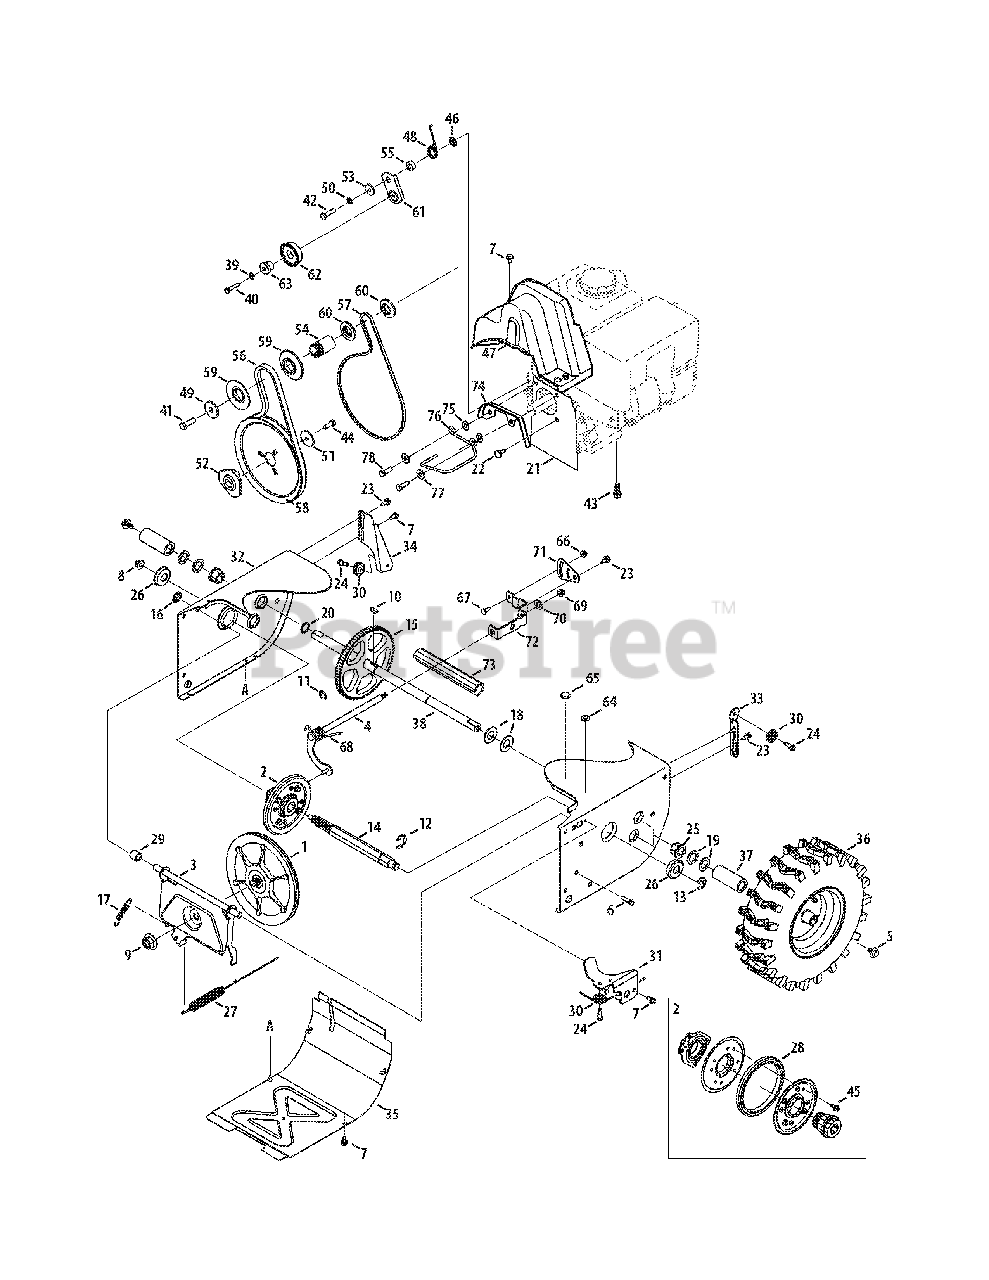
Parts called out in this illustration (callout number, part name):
1	Disc Assembly, Friction Wheel
2	Friction Wheel Assembly, 5.5 OD
3	Support Bracket, Friction Wheel
4	Shift Assembly, Rod
5	Screw, 5/16-24, .750, Gr5
6	Screw, 1/4-20, 1.000
7	Screw, 1/4-20 x .625
8	Nut, Flange Lock, 3/8-16, Nylon
9	Nut, Flange, 5/8-18
10	Key, Hi Pro, 3/16 x 3/4 Dia.
11	E-ring, .500 Dia.
12	E-ring, Retaining, .875 Dia.
13	E-ring, .750 Dia.
14	Hex Shaft, .8125, 7-Tooth
15	Gear, 80-Tooth
16	Speed Nut, .500
17	Extension Spring
18	Washer, Flat, .760 x 1.490 x .060
19	Washer, Flat, .793 x 1.24 x .060
20	Washer, Flat, .75 x 1.00 x .060
21	Plate, Cover
22	Shoulder Screw
23	Screw, Shoulder, .37 x .105, 1/4-20
24	Screw, 1/4-28, .375
25	Bearing, Hex Flange x .75 ID
26	Bearing, Ball, 17 x 40 x 12
27	Clutch Cable, Wheel, 44.95"
28	Rubber, Friction Wheel, 5.5 OD
29	Spacer, .508 ID x .75 OD x .68
30	Roller, Cable
31	Front Guide Bracket, Auger Cable
32	Frame
33	Guide Bracket, Auger Cable
34	Guide Bracket, Drive Cable
35	Cover, Frame
36	LH Wheel Assembly
36	RH Wheel Assembly
37	Spacer, 1.25 x .75 x 3.0
38	Axle, .75 x 22"
39	Washer, Lock, 1/4
40	Hex Screw, 1/4-20, 1.25, Gr5
41	Hex Screw, 3/8-24, 1.25, Gr8
42	Hex Screw, 5/16-24, 1.25, Gr5
43	Screw, Sems, 3/8-16, 1.00
44	Hex Screw, 5/16-24, .875, Gr8
45	Screw, 5/16-18 x .750
46	Nut, Push-on, .25 Dia.
47	Cover, Belt
48	Spring, Torsion, .850 ID x .354
49	Washer, Flat, .45 x 1.5 x .172
50	Washer, Lock .3125
51	Washer, Flat, .34 x 1.50 x .150
52	Pulley, Adapter, .75 Dia.
53	Spacer, Shoulder, .317 x .50 x .102
54	Spacer, .875 ID x 1.185 OD
55	Spacer, .340 x .750 x .360
56	Belt, Auger Drive
57	Belt, Wheel Drive
58	Pulley, Auger Drive, 8.1 x .5
59	Pulley, Half, V x 2.600 OD
60	Pulley, Half, 3/8-V x 1.7160 OD
61	Idler Bracket, Wheel Drive
62	Idler Pulley Assembly
63	Spacer, Shoulder, .26 x .79 x .538
64	Plug, 3/8 ID
65	Plug, 1/2 ID
66	Nut, Flange Lock, 1/4-20, Nylon
67	Hex Screw, 1/4-20, .620, Gr5
68	Spring, Torsion, .750 ID x .968
69	Nut, Flange Lock, 5/16-18, Nylon
70	Wash., Flat, .469 x .875 x .105
71	Pivot Bracket, Speed Selector
72	Shift Bracket, Speed Selector
73	Spacer, Axle
74	Belt Cover
75	Washer, Flat, .330 x .687 x .030
76	Belt Guide
77	Flat Washer, .349 x .879 x .063
78	Screw, 5/16-24 x 1.00
